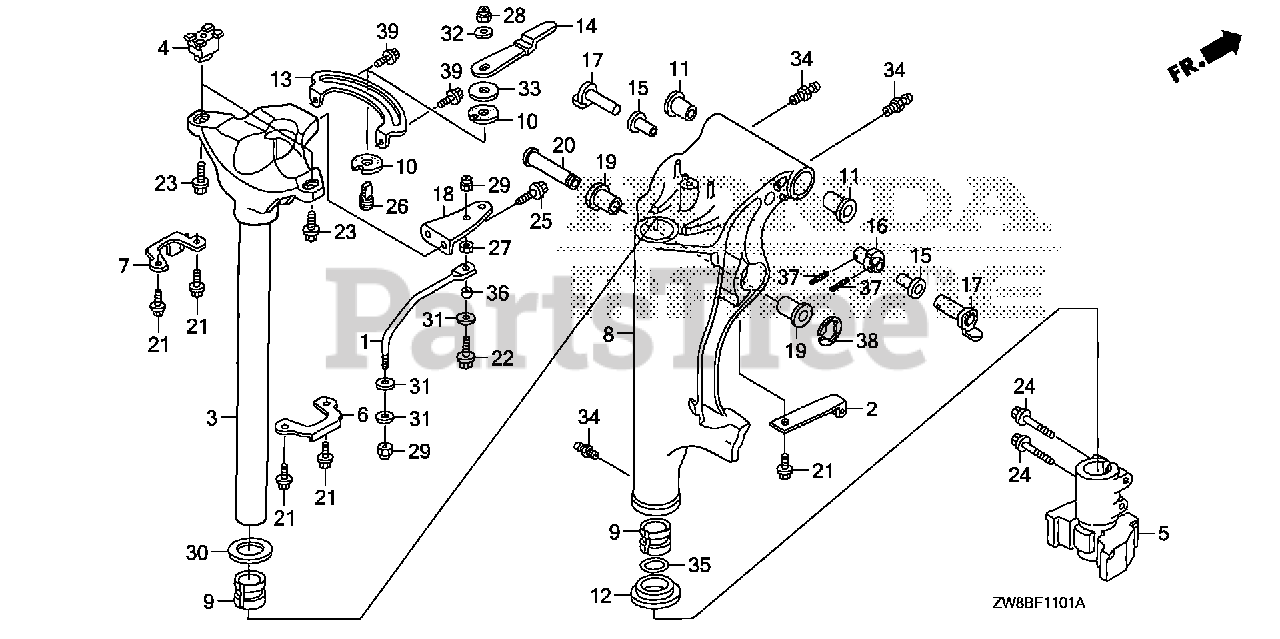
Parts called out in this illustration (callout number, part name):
1	ROD, STEERING
2	SPRING, CLICK
3	FRAME, MOUNTING (L)
4	RUBBER, MOUNTING (UPPER)
5	RUBBER, MOUNTING (LOWER)
6	COVER, MOUNTING RUBBER (UPPER)
7	COVER, MOUNTING RUBBER (UPPER) (PT)
8	CASE, SWIVEL *NH282MU* (L)(PT) (OYSTER SILVER METALLIC-U)
9	LINER, SWIVEL CASE
11	BUSH, SWIVEL CASE
12	COLLAR, SWIVEL CASE
15	BUSH, TILT ARM
16	BRACKET, TILTING
17	STOPPER, TILT
18	PLATE, STEERING
19	BUSH, CYLINDER (LOWER)
20	PIN, CYLINDER (UPPER)
21	BOLT, FLANGE (6X12) Use from Frame SN 1005249.
22	BOLT (3/8-24 UNF)
23	BOLT, FLANGE (10X25)
24	BOLT, FLANGE (8X45)
25	BOLT, FLANGE (10X20)
27	NUT (3/8-24 UNF)
29	NUT, SELF-LOCK (3/8-24UNF)
30	WASHER, THRUST
31	WASHER (10MM)
34	NIPPLE, GREASE
35	O-RING (34X2.4)
36	COLLAR, STEERING ROD
37	PIN, SPRING (2.5X20)
38	E-RING (15MM)
